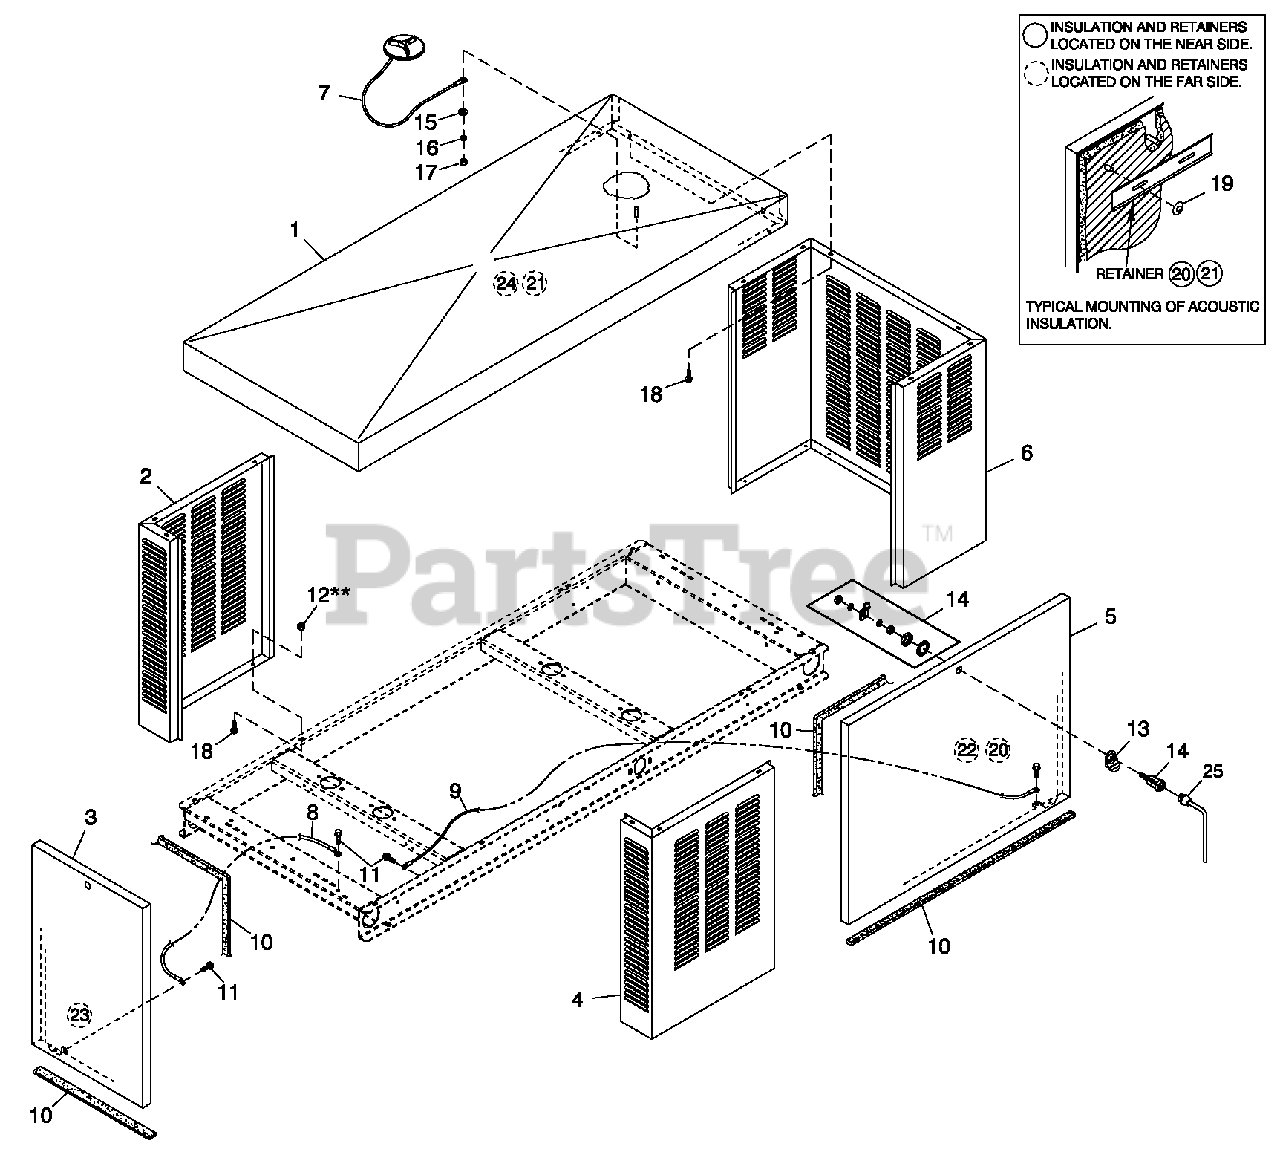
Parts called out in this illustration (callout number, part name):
1	ROOF C1 CPL
2	CORNER POST LH SIDE C1 CPL
3	DOOR REAR C1 CPL
4	CORNER POST RH SIDE C1 CPL
5	DOOR LH & RH SIDE C1 CPL
6	DUCT FRONT DISCHARGE C1 CPL
7	ASSEMBLY COVER ACCESS
8	ASSY WIRE 14AWG 13.8" GRN/YEL
9	ASSY WIRE 14AWG 33.5" GRN/YEL
10	GASKET EXTRUDED TRIM (356" LG)
11	SCREW HWHTF M6'1.0 X 16
12	NUT HEX LOCK M6'1.0 SS NY INS
13	TAB PULL
14	VISE'ACTION LATCH SLOTTED CIR
15	WASHER FLAT 1/4'M6 ZINC
16	WASHER LOCK M6'1/4
17	NUT HEX 1/4'20 STEEL
18	SCREW THF M6'1 X 16 N WA Z/JS
19	WASHER SELF LOCKING DOME
20	RETAINER INSULATION (820)
21	RETAINER INSULATION (450)
22	INSULATION SIDE DOOR C1
23	INSULATION REAR DOOR C1 CPL
24	INSULATION ROOF C1 CPL
25	KEY VISE'ACTION LATCH SLOT CIR
